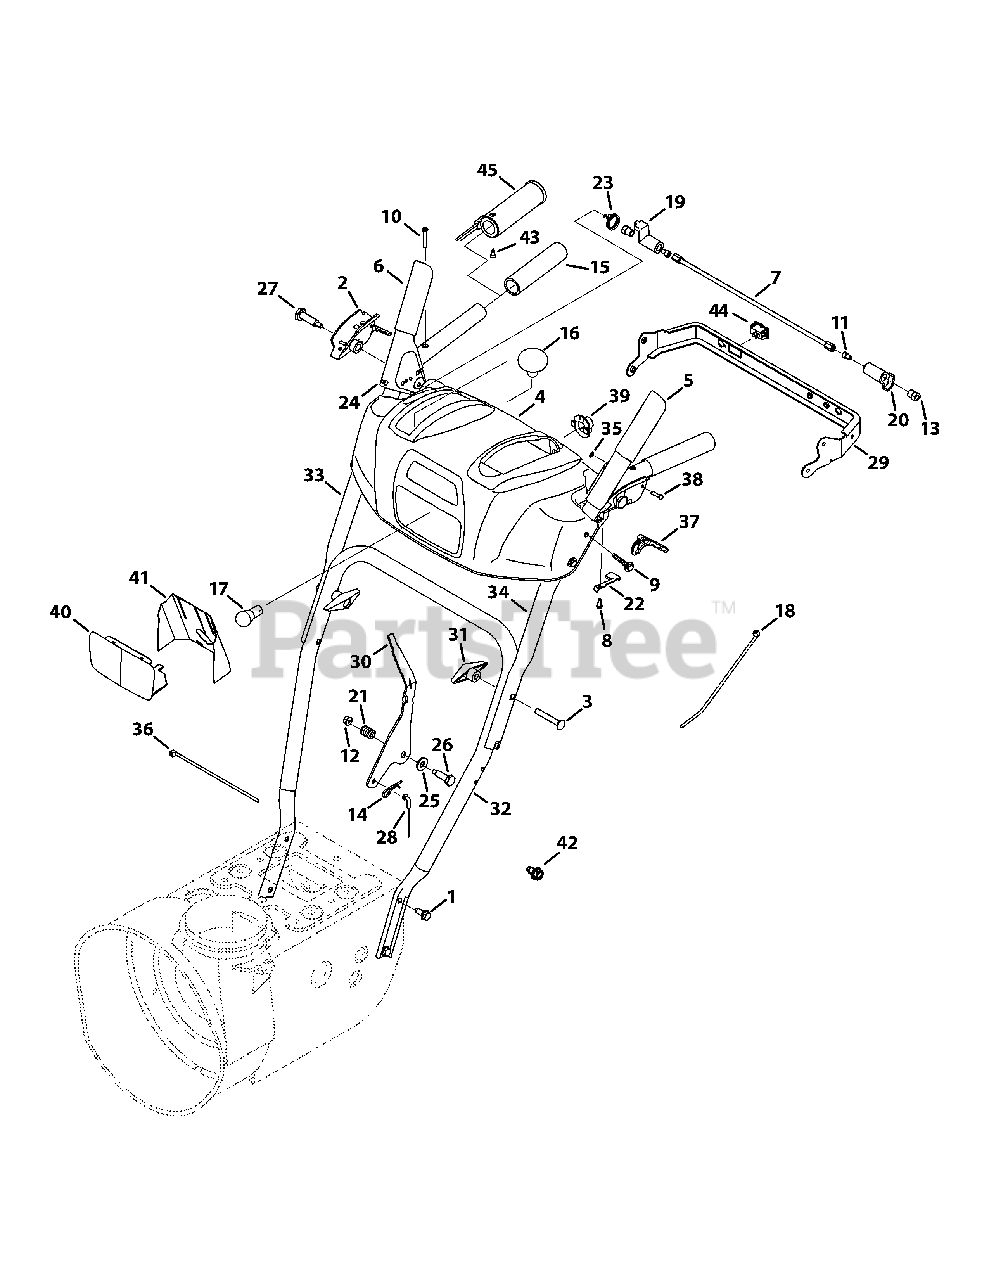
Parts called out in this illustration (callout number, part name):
1	Hex Screw, 5/16-18 x .750
2	Handle Clutch Lock LH Assy
2	Handle Clutch Lock RH Assy
3	Carriage Screw, 5/16-18 x 2.25
4	Handle Panel, includes Ref. 40 & 41
5	Handle Engagement Assembly LH
6	Handle Engagement Assembly RH
8	Screw, 8-16 x 0.50
9	Screw, 1/4-20 x 1.625
10	Screw, 10-24 x 1.375
11	Socket Screw, 1/4-20 x .50
12	Flange Lock Nut, 1/4-20
13	Shoulder Nut, 1/4-20
14	Click Pin, .092 x 1.64
15	Handle Grip
16	Shift Knob
18	Cable Tie
20	Clutch Lock Cam
21	Compression Spring
22	Clutch Lock Spring
23	Torsion Spring
24	Rubber Bumper
25	Flat Washer, .385 x .87 x .06
26	Shoulder Screw, .374 x 1.05
27	Shoulder Screw, 1/4-20 x 1.345
28	Speed Cable Selector
29	Panel Bracket
30	Shift Lever
31	Wing Knob
32	Lower Handle
33	Upper Handle RH
34	Upper Handle LH
36	Cable Tie
37	Clutch Trigger
39	Light Socket
41	Lens Label
42	Screw, TT, 1/4-20 x .500 (For ground wire)
43	AB Screw, #10-16 x .625 (530 SWE)
44	Heated Grip Switch (530 SWE)
45	Heated Grip (530 SWE)
